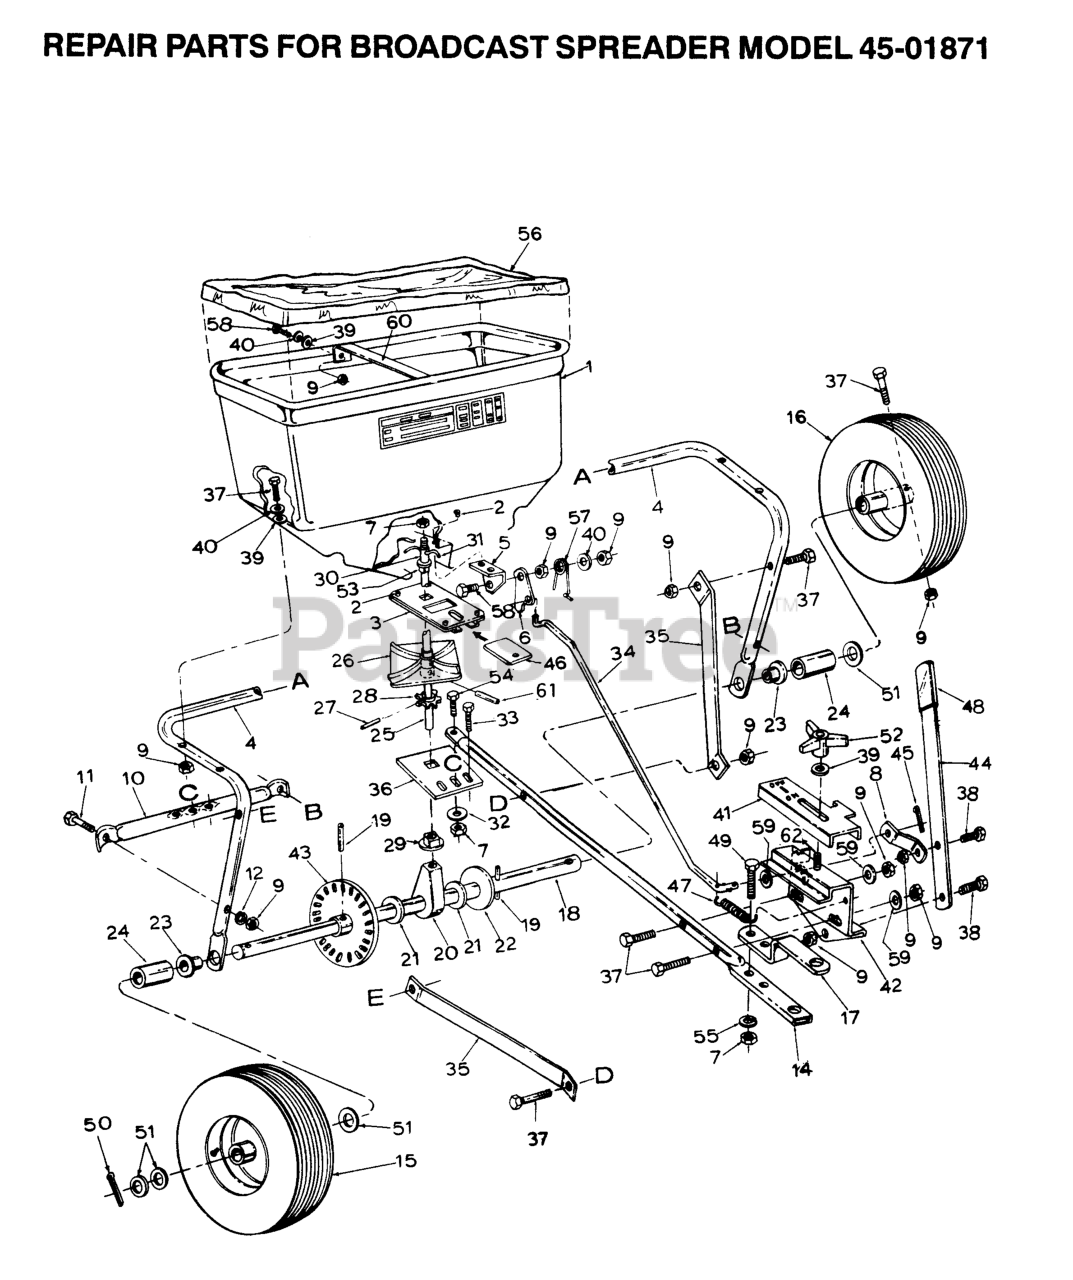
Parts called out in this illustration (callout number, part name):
15	WHEEL, CPL.
16	WHEEL CPL.
17	Bracket, Hitch
19	SPRING PIN
27	SPRING PIN
32	WASHER
38	BOLT FLANGE - M6X20
39	WASHER, NYLON
40	WASHER - M6
41	METERING GAUGE
43	GEAR, ASSY
46	PLATE, CLOSURE
49	HEX BOLT
55	Spring Washer
58	SCREW M6S 6X20
59	WASHER - M6
61	SPRING PIN
